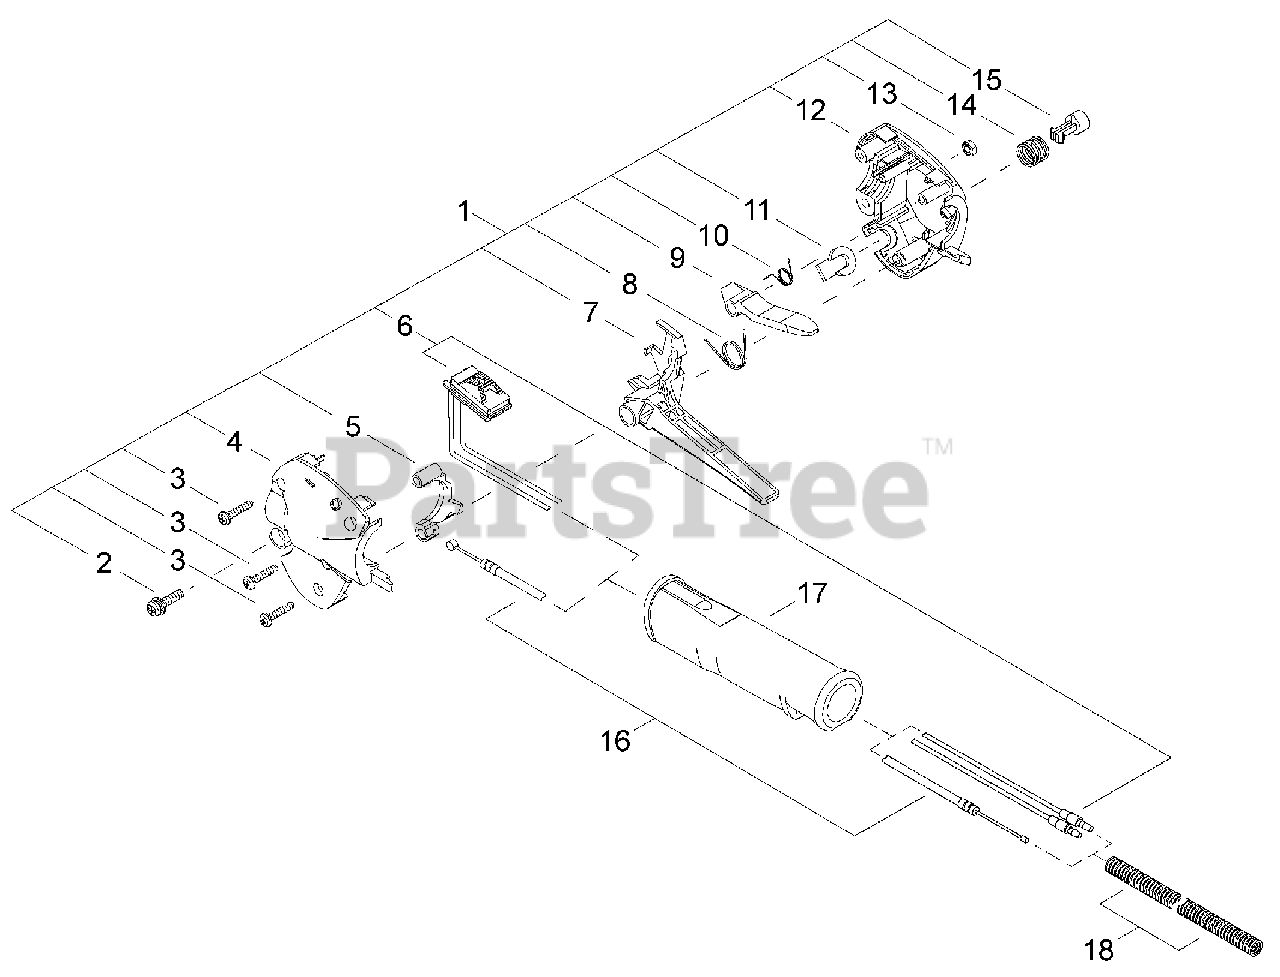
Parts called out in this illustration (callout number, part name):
1	THROTTLE LEVER ASSY
2	SCREW - 5X20
3	SCREW - 4X20 -- TAPPING
4	HANDLE, CONTROL - LEFT
5	LOCKOUT, THROTTLE
6	SWITCH, IGNITION
7	TRIGGER, THROTTLE
8	SPRING
9	LEVER, TRIGGER LOCKOUT
10	SPRING
11	PLUG
12	HANDLE, CONTROL - RIGHT
13	NUT - 5
14	SPRING
15	BUTTON, THROTTLE LOCK
16	CABLE, THROTTLE
17	GRIP - REAR
18	TUBE
